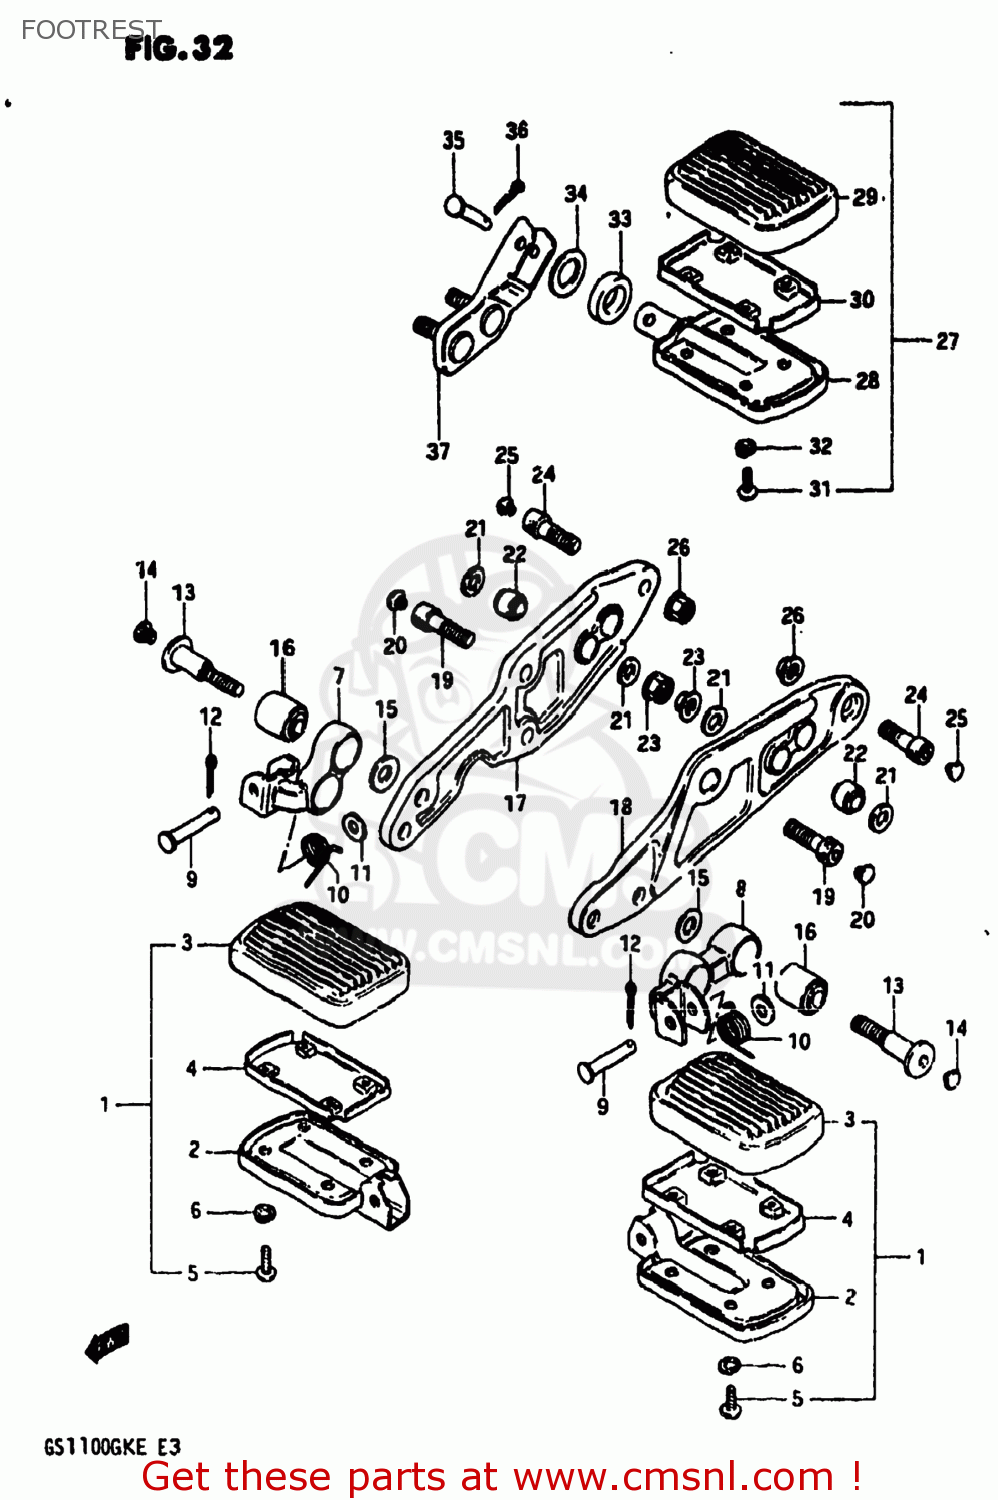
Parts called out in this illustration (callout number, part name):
1	FOOTREST ASSEMBLY,FRONT
2	HOLDER,FRONT FOOTREST
3	RUBBER,FOOTREST
4	PLATE FOOTREST
5	SCREW(5X14)
6	LOCK WASHER
7	BAR,FRONT FOOTREST,RIGHT
8	BAR,FRONT FOOTREST,LEFT
9	PIN
10	SPRING
11	WASHER
12	PIN 20X20
13	BOLT
14	CAP
15	WASHER (10.1X22X3.2)
16	BUSH(10.2X25X19)
17	BRACKET,MUFFLER,RIGHT
18	BRACKET,MUFFLER,LEFT
19	BOLT
20	CAP
21	WASHER(10.5X20X3.2)
22	BUSH
23	NUT
24	BOLT
25	CAP
26	NUT
27	FOOTREST ASSEMBLY,PILLION
28	BAR,REAR FOOTREST
29	RUBBER,FOOTREST
30	PLATE FOOTREST
31	SCREW(5X14)
32	LOCK WASHER
33	CUSHION
34	WASHER (19.5X32X2)
35	PIN
36	PIN 20X20
